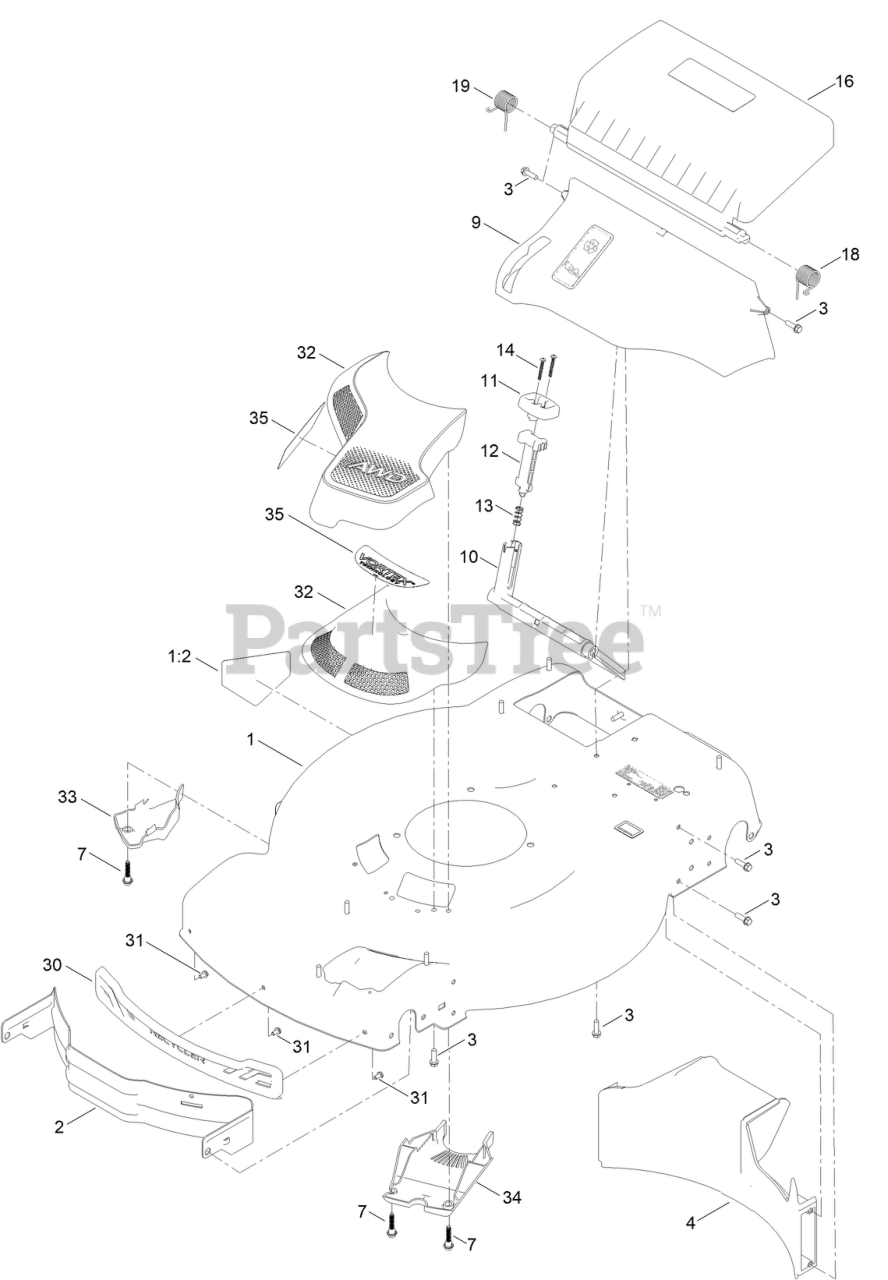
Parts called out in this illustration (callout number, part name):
1	HOUSING ASM
1:2	DECAL-DANGER
2	BAFFLE-FRONT
3	SCREW-PLASTITE, HWH
4	BAFFLE-REAR, RWD
7	SCREW-SHOULDER,HWH
9	ASM-CHUTE, IN MOLD
10	DEFLECTOR-RECYCLE
11	KNOB-RECYCLE
12	LATCH-RECYCLE
13	SPRING-COMPRESSION
14	SCREW-PPH
16	ASM-REAR DOOR, IN MOLD
18	SPRING-TORSION, LH
19	SPRING-TORSION, RH
30	BUMPER-FRONT
31	SCREW-PLASTIC, HWH
32	ASM-INTAKE, AWD
33	COVER-INTAKE, BOTTOM
34	COVER-BELT, LOWER (AWD)
35	DECAL-VORTEX AWD
